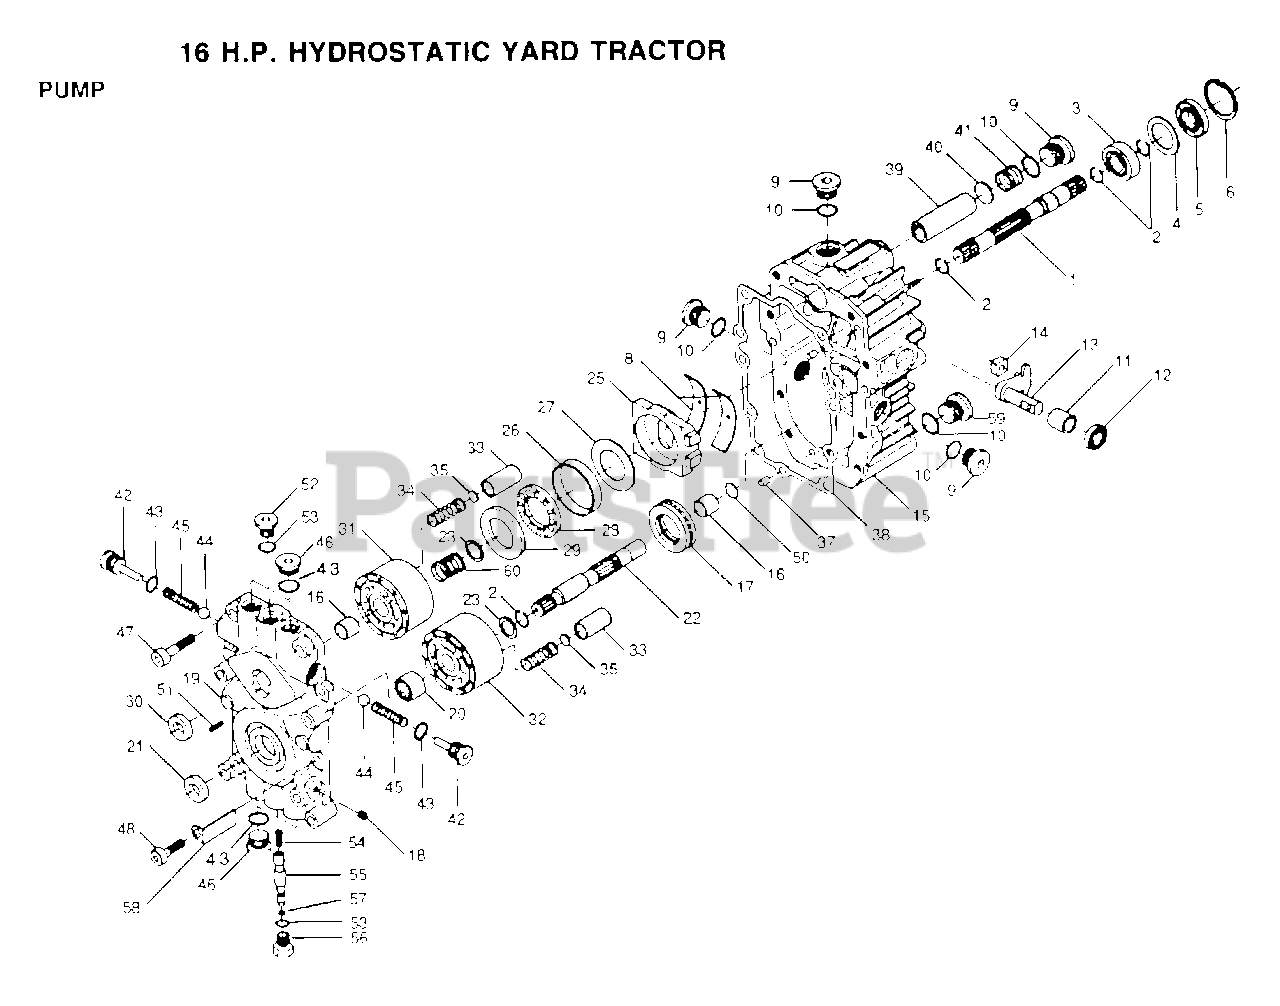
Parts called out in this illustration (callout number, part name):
1	SHAFT.PU.2003022
2	RETAINIANG RING-(2003016)
3	BALL BEARING
4	SPACER
5	SEAL LIP
6	RING.RET.2003052
8	CRADLE BEARING (2003023)
11	BEARING
12	SEAL.9008000-0126
13	TRUNION ARM (2003005)
14	GUIDE.2000015.HYD
16	JOURNAL BRG(2003071)
19	CENTER SECTION
20	NEEDLE BEARING
21	LIP SEAL-9008000-0127
22	SHAFT
23	WASHER
30	SEAL LIP
31	CYLINDER BLOCK
32	CYLINDER BLOCK(70331)
34	PISTON SPRING
35	WASHER.TR.2003019
37	PIN
38	GASKET.20030600
39	FILTER
40	WASHER (2000011)
41	SPRING
45	SPRING.2003012.HY
46	PLUG
47	SCREW9007314-0808
50	WASHER
51	PIN
52	PLUG
53	O RING
56	BYPAS KT 25130011
57	O RING (9004175-0027)
58	ADHESIVE LABEL
59	PLUG
